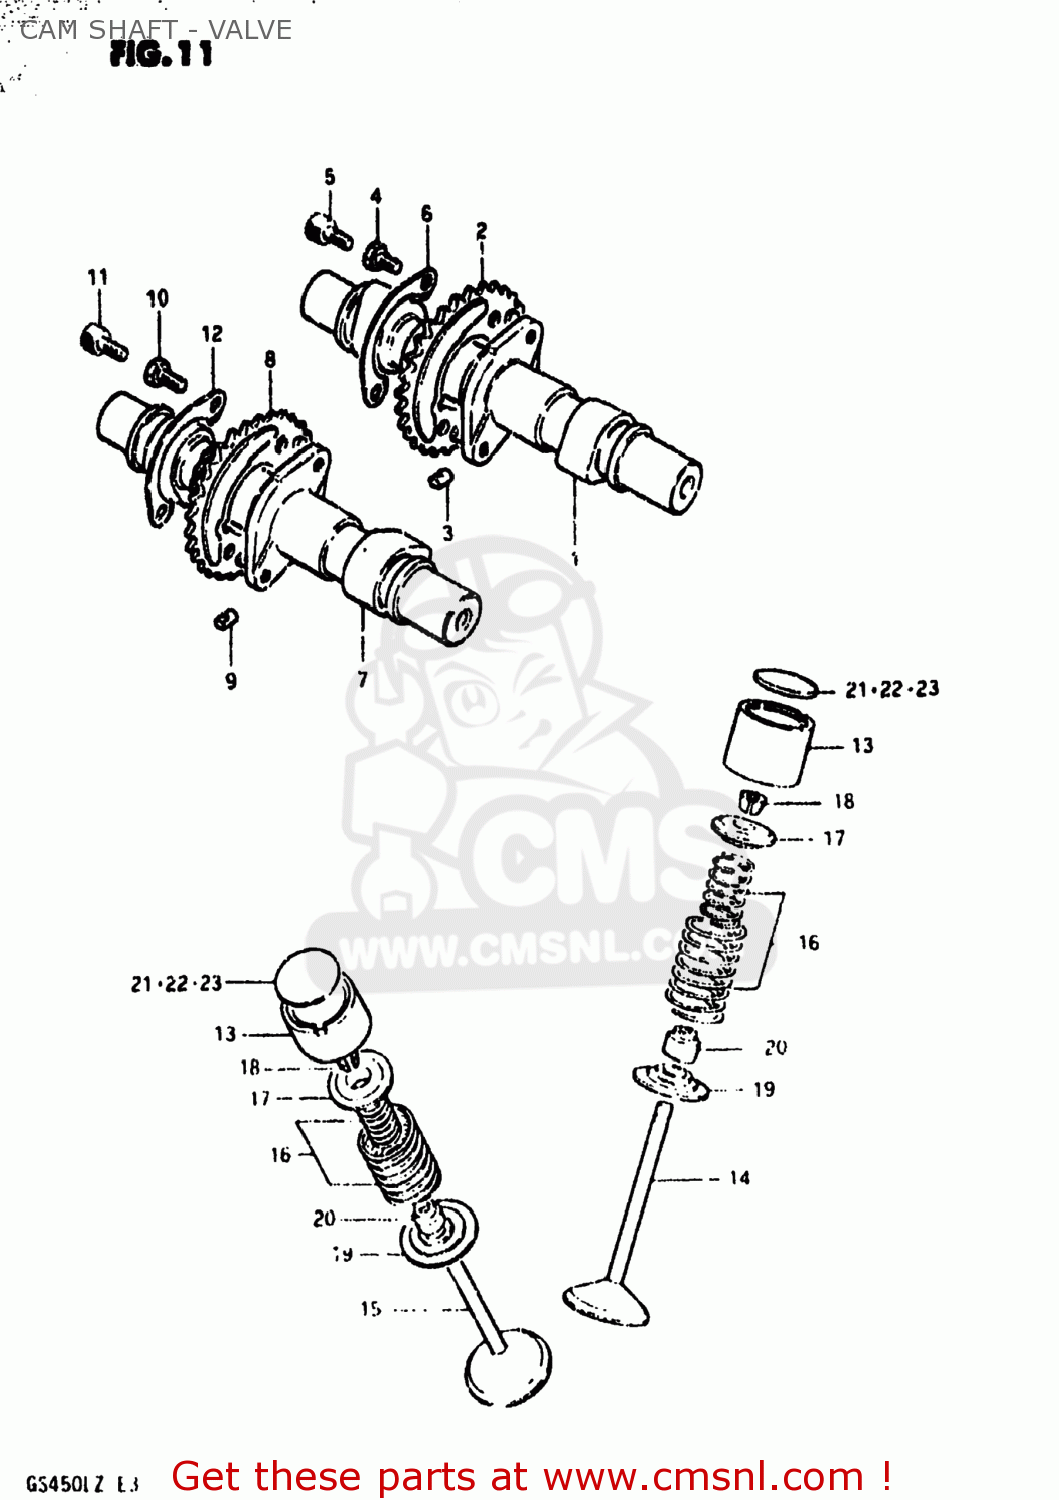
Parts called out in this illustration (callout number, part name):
1	CAMSHAFT
2	SPROCKET,CAMSHAFT
3	PIN,SPROCKET
4	BOLT(6X12.5)
5	BOLT 6X11
6	WASHER,CAM CHAIN SPROCKET
7	CAMSHAFT,EXHAUST
8	SPROCKET,EXHAUST CAMSHAFT
9	PIN,SPROCKET
10	BOLT(6X12.5)
11	BOLT 6X11
12	WASHER,CAM CHAIN SPROCKET
13	TAPPET
14	VALVE,INTAKE
15	VALVE,EXHAUST
16	SHIM,TAPPET
17	RETAINER,VALVE SPRING
18	COTTER VALVE
19	SEAT,VALVE SPRING
20	SEAL,OIL(7X14.4X9)
21	SHIM,TAPPET
22	SHIM,TAPPET
23	SHIM,TAPPET
24	SHIM SET,TAPPET
25	CASE
